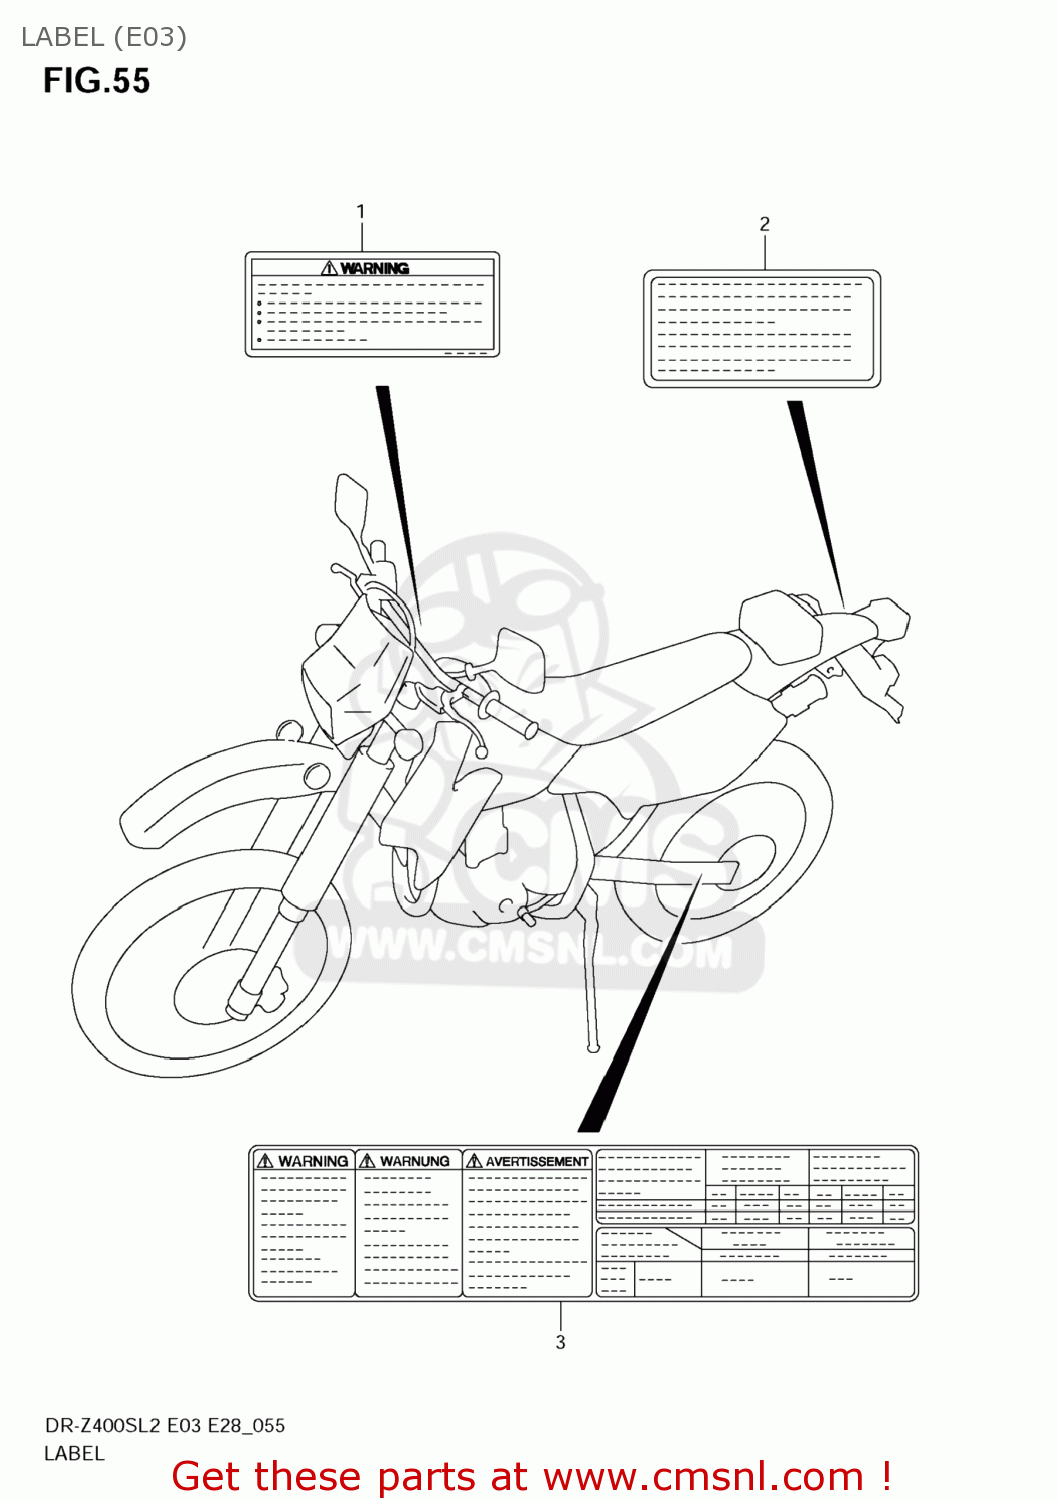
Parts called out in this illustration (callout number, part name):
1	LABEL,GENERAL WARNING
2	LABEL,MANUAL NOTICE
3	LABEL,TIRE INFORMATION
4	MANUAL,OWNER'S
